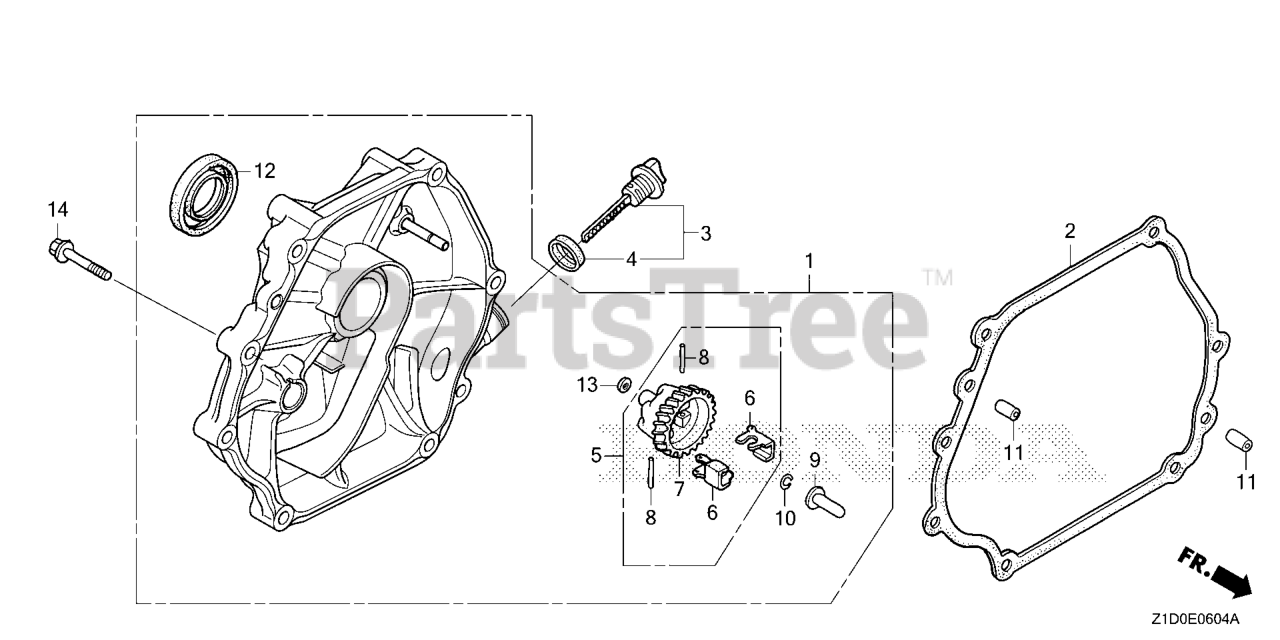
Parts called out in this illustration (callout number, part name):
1	COVER ASSY., CRANKCASE (Q-TYPE)
2	GASKET, CASE COVER
3	CAP ASSY., OIL FILLER
4	GASKET, OIL FILLER CAP
5	GOVERNOR ASSY. (STD)
6	WEIGHT, GOVERNOR
7	HOLDER, GOVERNOR WEIGHT
8	PIN, GOVERNOR WEIGHT
9	SLIDER, GOVERNOR
10	CLIP, GOVERNOR HOLDER
11	PIN, DOWEL (8X12)
12	OIL SEAL (30X46X8) (NOK ASIA)
13	WASHER, PLAIN (6MM)
14	BOLT, FLANGE (8X35)
